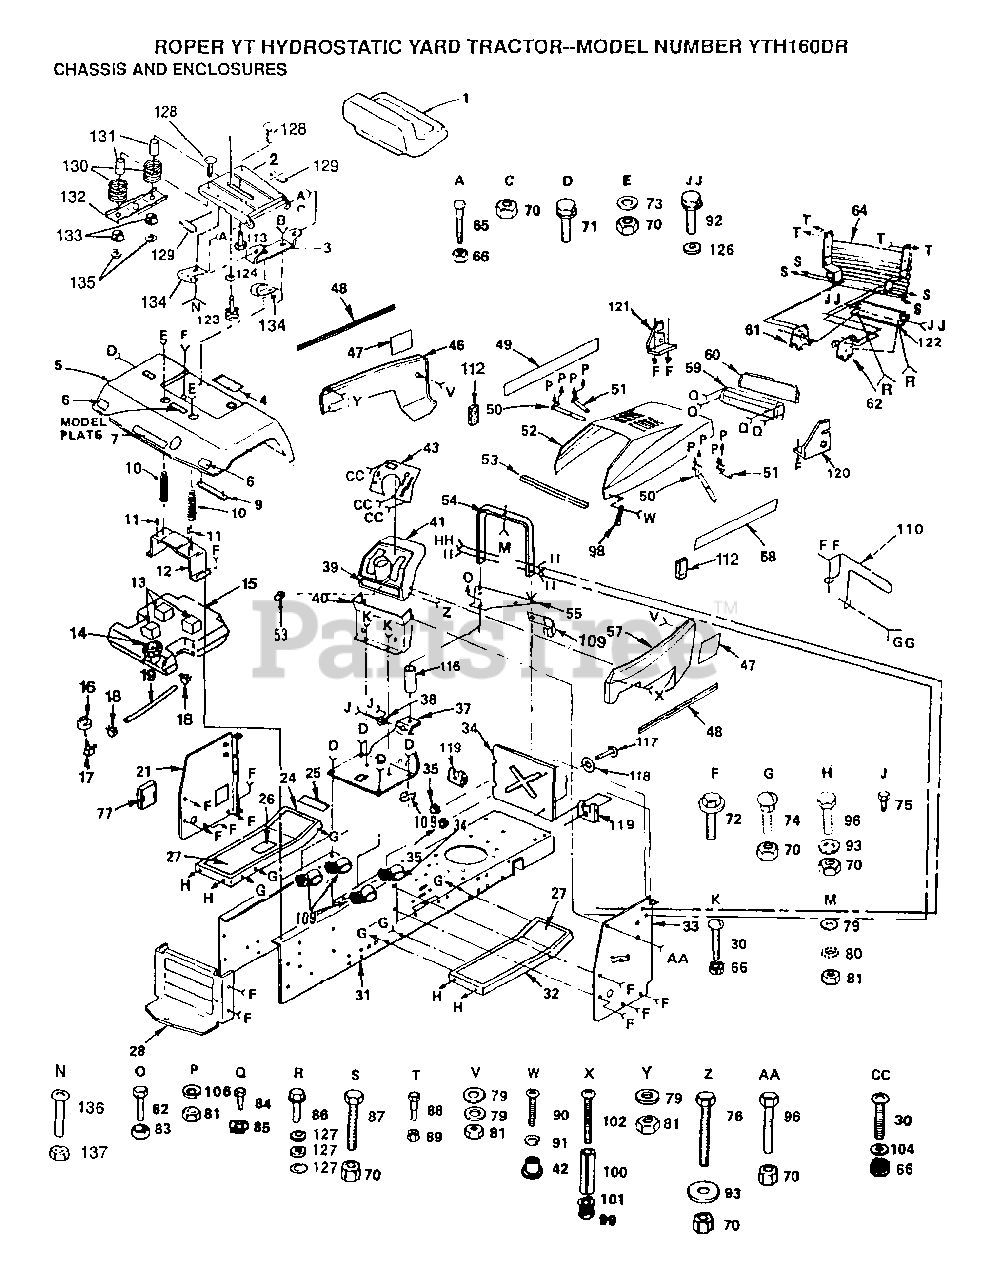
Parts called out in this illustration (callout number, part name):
6	REFLECTOR-TAIL YT
11	NUT-PUSH YT
13	PAD-SPACER T
16	BUSHING OUTLET T
17	FUEL TANK STEM GT
21	DASH PANEL T
25	DECAL T
26	DECAL DRIVE BELT
30	SCREW
37	SADDLE
40	LOWER DASH
42	WELDNUT
53	FOAM STRIP T
60	LENS LT
61	SUPPORT LH YTH
62	SUPPORT RH YTH
71	SCREW LT
72	SCREW
73	WASHER
74	BOLT
76	BOLT
77	COVER ACCESS
79	WASHER PM
82	BOLT
85	"""J"" FASTENER LT"
86	SCREW
87	BOLT
88	BOLT T
90	SCREW
91	LOCKWASHER
92	SCREW
93	WASHER
98	HOOD LATCH T
100	SPACER LT
101	WASHER
102	SCREW
104	WASHER
109	CLIP T
110	GUARD MUFFLER HYT
112	STRIP - FOAM
116	SPACER
118	RETAINER LT
119	RECEPTACLE LT
120	SUPPORT RH YTH
121	SUPPORT LH YTH
122	STRAP GRILL
123	"KNOB 1/2"" YT"
124	WASHER
126	LOCKWASHER GT
127	WASHER M
128	BOLT
129	STRIP FORM
130	SPRING
131	SPACER SPLIT
132	BRKT SWITCH
133	BUSHING
135	NUT T
137	"NUT,KEPS"
